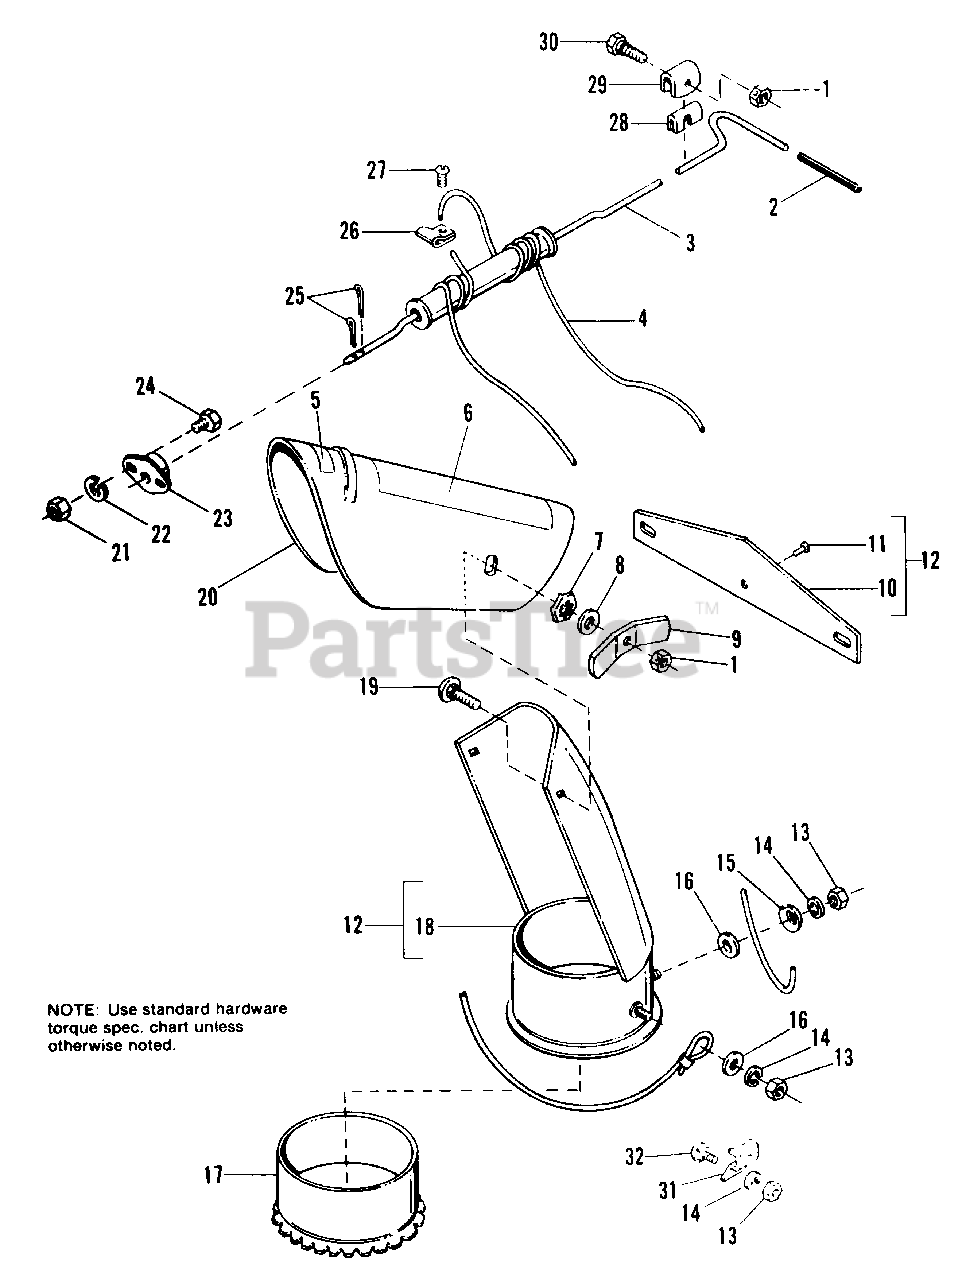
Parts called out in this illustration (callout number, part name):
1	LOCKNUT, Hex, 5/16-18 (Qty. 1 used on 990796, 990869 & 990870)
2	GRIP, Handle
3	ROD ASSY., Spout Control
3	ROD ASSY., Spout Control (1690378 Only)
4	CABLE ASSY.
5	DECAL, Warning
6	DECAL, Safety
7	LOCKWASHER, Pyramdial Type, 3/8
7	LOCKWASHER, Dished Type, 3/8
8	WASHER, Plain, 5/16
9	NUT, Wing, 5/16-18
10	DEFLECTOR, Snow
11	RIVET, 1/8 Dia.
12	SPOUT ASSY., W/Deflector
13	NUT, Hex, Full, 5/16-18 (Qty. 2 used on 1690305 & 1690378 Only)
14	LOCKWASHER, 5/16 (Qty. 2 on 1690305 & 1690378 Only)
15	WASHER, Cup
16	WASHER, Plain, 1/4
17	LINER (1690378 Only)
18	SPOUT ASSY.
19	BOLT, Carriage, 5/16-18 x 3/4
20	EXTENSION, Spout
21	NUT, Hex, Full, 1/4-20
22	LOCKWASHER, 1/4
24	CAPSCREW, Hex Hd., 1/4-20 x 1/2
25	PIN, Cotter, 1/8 x 3/4
27	SCREW, Taptite, 1/4-20 x 3/8
30	CAPSCREW, Hex Hd., 5/16-18 x 1-1/4
31	PLATE, Hold Down
32	BOLT, Carriage, 5/16-18 x 3/4
